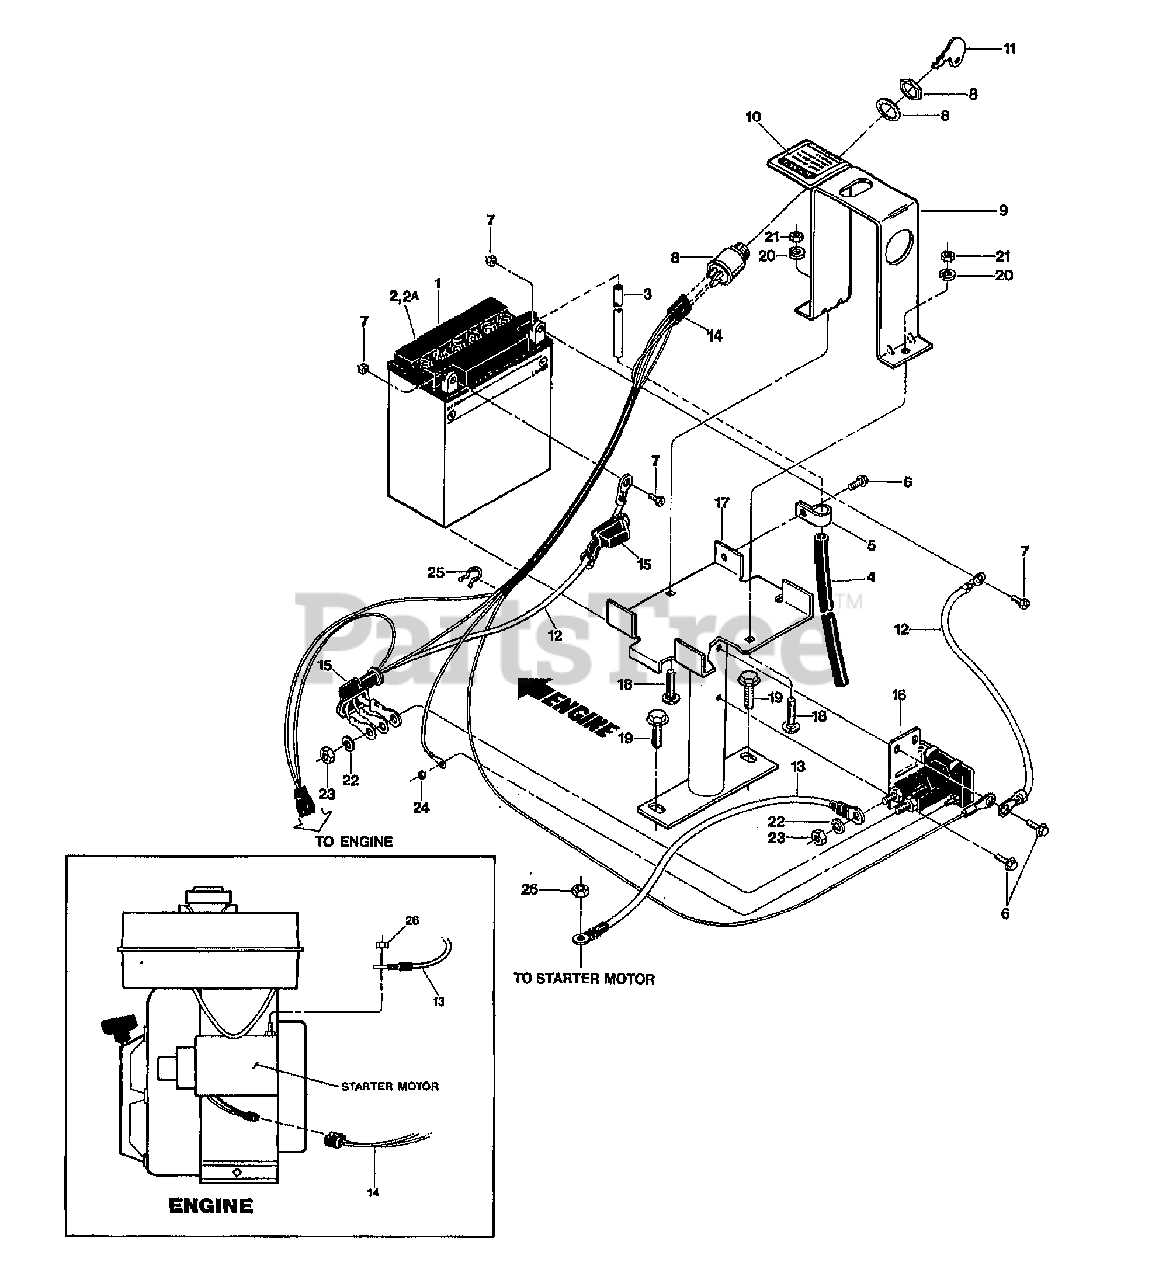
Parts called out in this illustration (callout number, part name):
1	BATTERY
2	CAP-YELLOW
2A	CAP-BATTERY WHITE (PONY)
3	TUBE-VENT BATTERY/HSE
4	TUBING-RUBBER (HARD PLASTIC)
5	CLAMP
6	SCR-HWH 1/4-20 X .5 STH
7	HDW PKG-BATTERY TERMINAL
8	ASSM-KEYSWITCH ELEC TLR
9	KEY PLATE/CLAMP PNT (INCL. DECAL, #10)
10	DECAL-KEYSWITCH TILLER
11	KEY-IGNITION
12	CABLE-BATTERY-12"
13	CABLE-BATTERY 15"
14	ASSM-WIRE HARNESS - AVAIL. AS COMPLETE ASSY. ONLY
15	BOOT-BATTERY CABLE
16	SOLENOID - INCL. NUTS & WASHERS FOR CABLES & WIRES
17	BRKT-BATTERY OPC PNT
18	SCR-CARR 1/4-20X1.25
19	SCR-HFLK 5/16-18X1.00 ZP
20	WASHER-LK .25 ZP
21	NUT-HEX 1/4-20 ZP
22	WASHER-LK .312 ZP
23	NUT-HEX 5/16-24
24	NUT W/LKWASHER #10-32 ZP
25	TIE-TWIST LOCK
26	NUT-HF/LK 1/4-20 ZP
